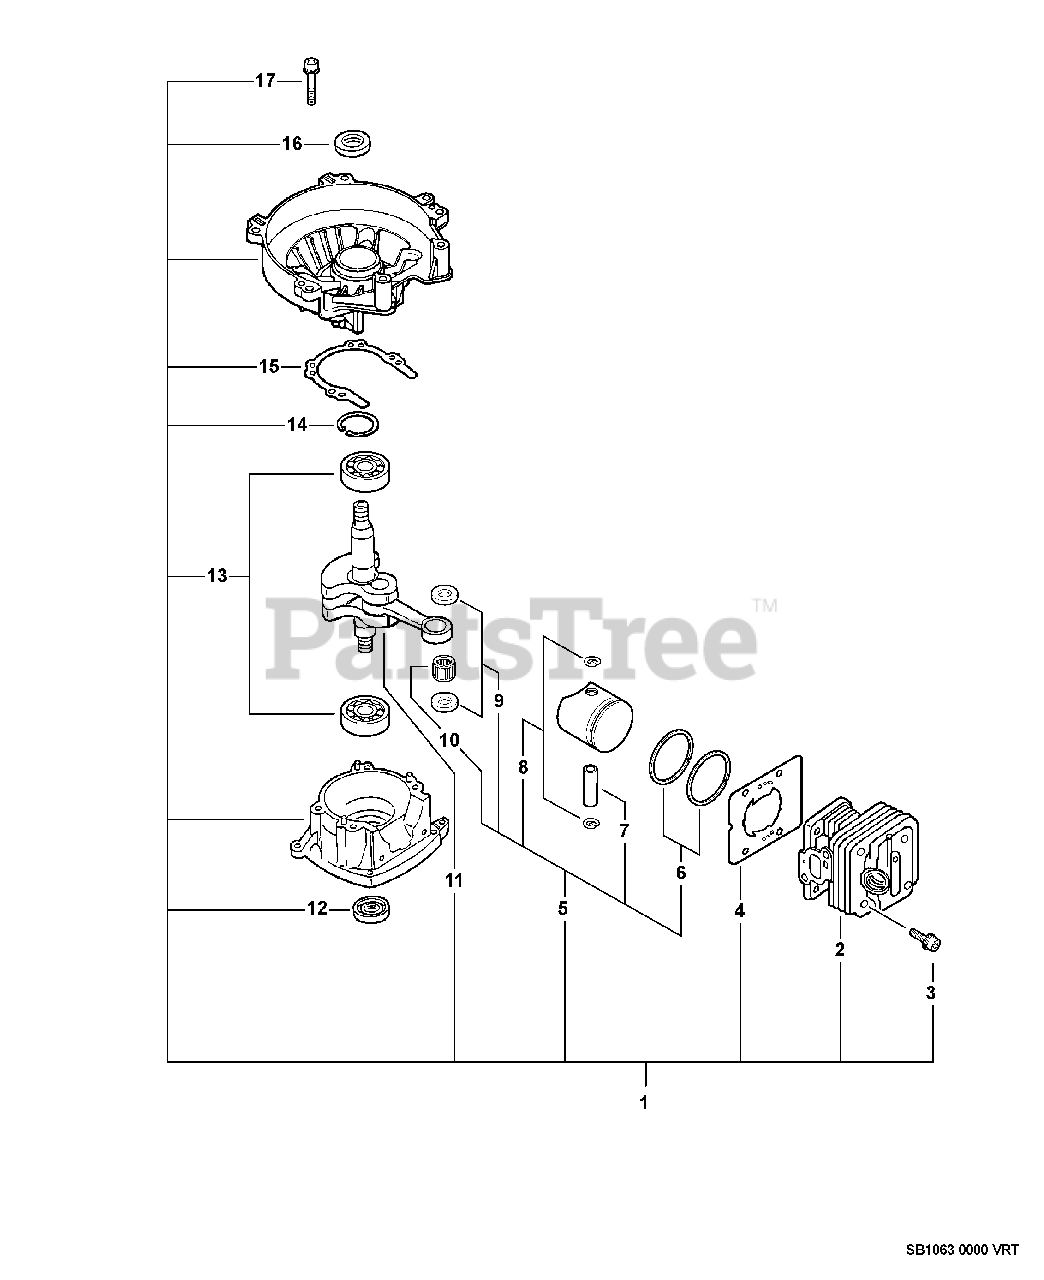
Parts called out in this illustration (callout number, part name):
1	SHORT BLOCK -- SB1063
2	CYLINDER
3	SCREW - 5X22
4	GASKET, CYLINDER
5	PISTON KIT
6	RING, PISTON
7	PIN, PISTON
8	RING, RETAINING
9	SPACER, PISTON
10	BEARING, NEEDLE - 8
11	CRANKSHAFT ASSY
12	SEAL, OIL
13	BEARING, BALL - 6001C3
14	RING, RETAINING - 28
15	GASKET, CRANKCASE
16	SEAL, OIL - 12
17	SCREW - 5X25
